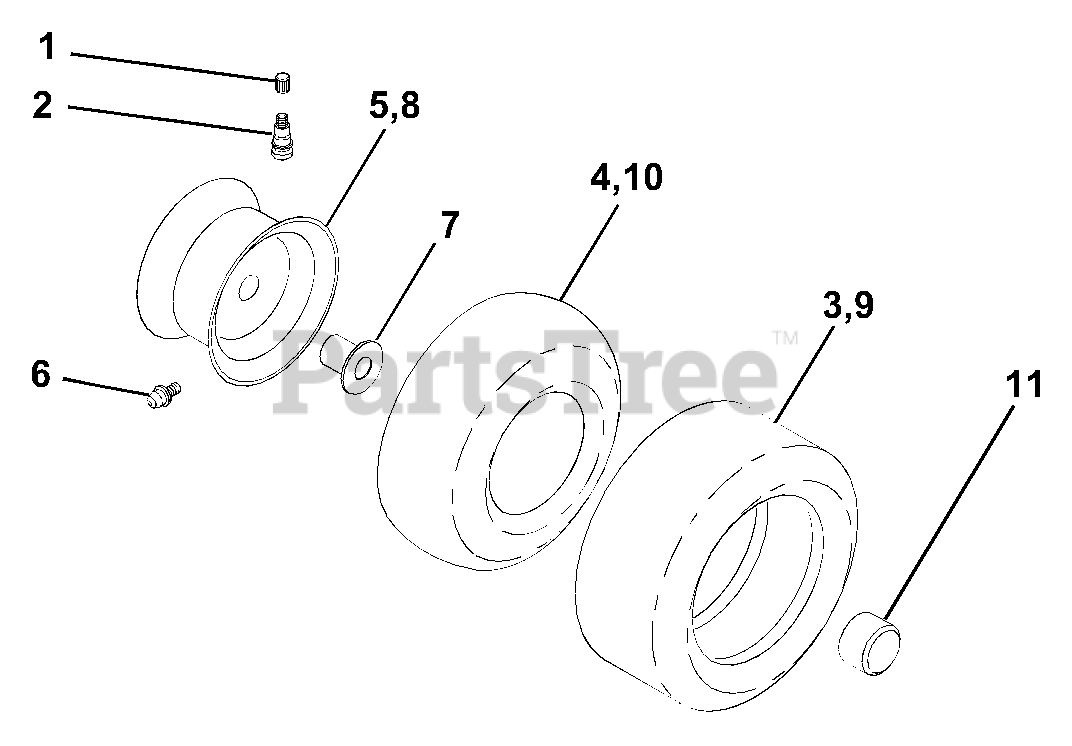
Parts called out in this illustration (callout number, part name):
1	Cap Valve Tire
2	Stem Valve
3	Tire F Ts 15 X 6 0 - 6 Service
4	Tube Front (Service Item Only)
5	Rim Asm 6"front Silver Service
6	Fitting Grease (Front Wheel Only)
7	Bearing Flange (Front Wheel Only)
8	Rim Asm 8"rear Silver Service
9	Tire R Ts 18x9 5-8 C Service
10	Tube Rear (Service Item Only)
11	Cap Axle Blk 1 50 X 1 00
